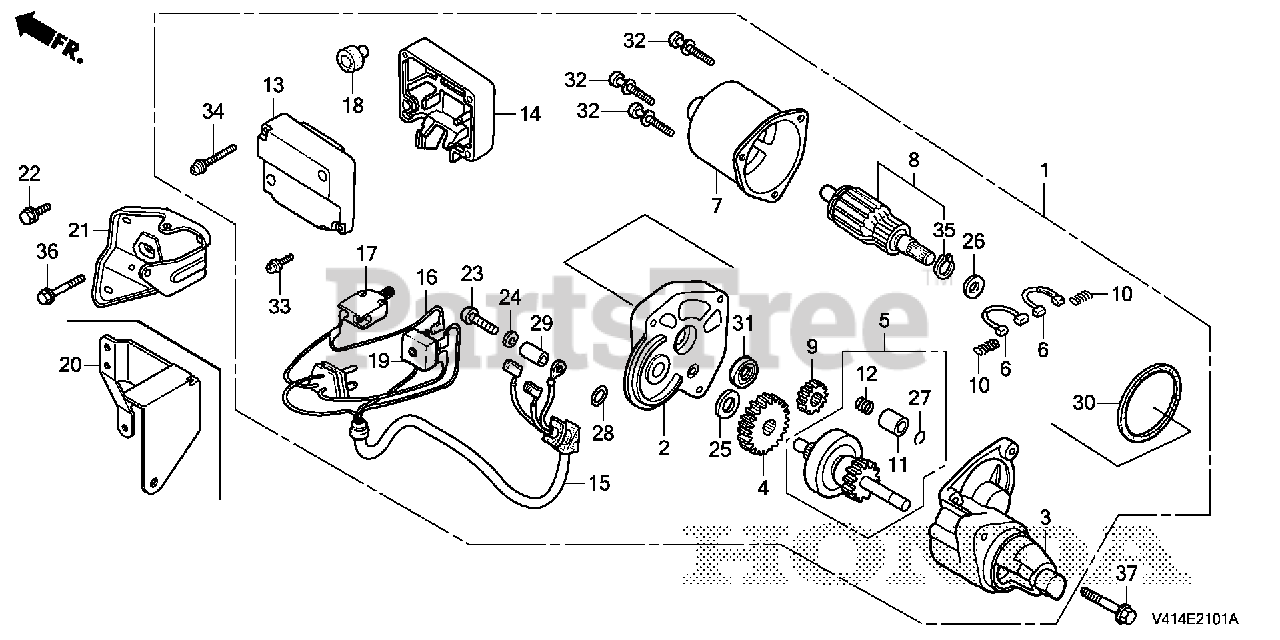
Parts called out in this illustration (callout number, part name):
1	STARTER MOTOR ASSY. (AC)
2	HOUSING, CENTER
3	HOUSING, PINION
4	GEAR, REDUCTION
9	GEAR, DRIVE
10	SPRING, BRUSH RETURN
11	STOPPER, PINION
12	SPRING, COIL
17	SWITCH, STARTER (A.C. 380V/16A)
17	SWITCH, STARTER (A.C. 250V/16A)
21	BRACKET, SWITCH BOX
22	BOLT, FLANGE (6X12) (CT200)
23	SCREW, TRUSS (4X30)
24	WASHER, STAR (4MM)
25	WASHER (A)
26	WASHER (B)
27	RING, RETAINING
32	SCREW-WASHER (5X30)
33	SCREW-WASHER (4X20)
34	SCREW-WASHER (4X30)
35	CIRCLIP (OUTER) (12MM)
36	BOLT, FLANGE (6X40)
37	BOLT, FLANGE (8X35)
